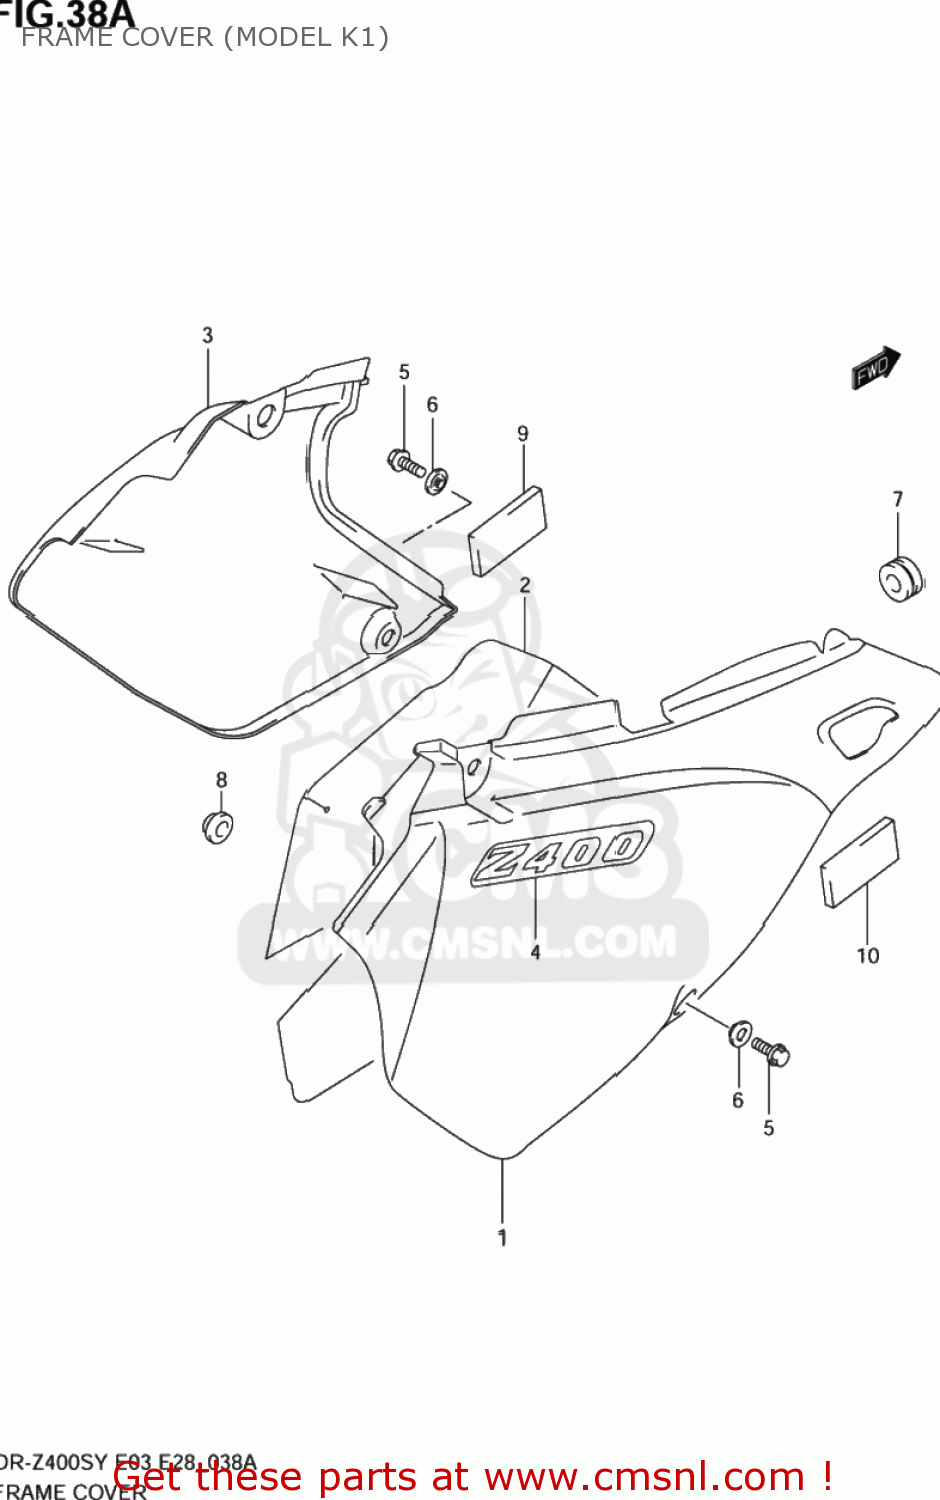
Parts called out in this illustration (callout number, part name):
1	COVER,FRAME,R(YELLOW)
2	SHIELD,FRAME COVER,R
3	COVER, FRAME LH (YELLOW)
4	EMBLEM,FRAME COVER
5	BOLT
6	WASHER
7	CUSHION
8	CUSHION
9	CUSHION,FRAME COVER,L
10	CUSHION
